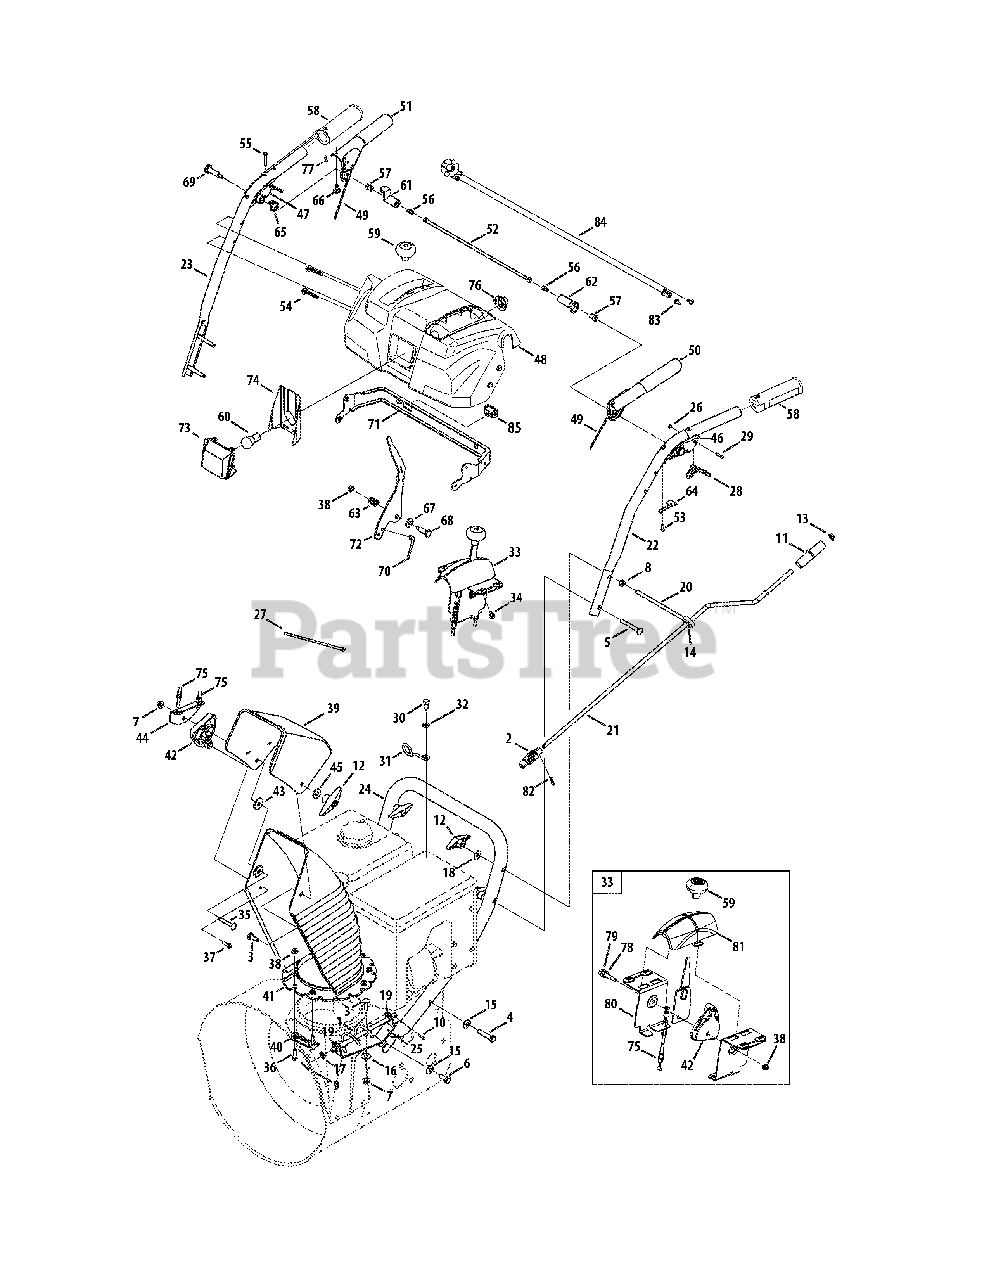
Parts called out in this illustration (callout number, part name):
1	Chute Crank Assembly
2	Joint Block Assembly
3	Screw, Carriage, 5/16-18 x 1.0
4	Screw, Hex, 3/8-16 x 2.00 Lock
5	Screw, Carriage, 5/16-18 x 2.5
6	Screw, Hex, 3/8-16 x 1.0 Lock, Gr5
7	Flange Lock Nut, 5/16-18
8	Hex Nut, 5/16-18
9	Pin, Bow-tie Cotter
10	Spring Pin
11	Knob, Crank
12	Wing Knob
13	Cap, Push, 3/8
14	Grommet, Rubber
15	Washer, Bel, .375 x .87 x .063
16	Washer, Flat, .349 x .879 .063
17	Washer, .375 x .738 x .063
18	Washer, Belleville, .34 x .872 x .06
19	Plastic Bushing, .380 I.D.
22	Handle, Upper - LH
23	Handle, Upper - RH
24	Handle, Lower
25	Chute Crank Bracket
26	Ring, Retainer
27	Cable Tie
30	Hex Head Screw, MB 1.25
31	Cable Guide
32	Flat Washer, .330 x .630 x .0635
33	2-Way Chute Control™ Assy
34	Hi-Lo Screw, 1/4-15 x 0.5
35	Bolt, Carriage, 5/16-18 x 1.75
36	Screw, 1/4-20 x 1.00
37	Hi-Lo Screw, 1/4-15 x .75
38	Flange Lock Nut, 1/4-20
39	Upper Chute
40	Chute, Flange Keeper
41	Lower Chute
42	Chute Tilt Cable Guide
43	Flat Washer
44	Cable Bracket
45	Washer, Flat, .349 x .879
46	Handle Clutch Lock - LH
47	Handle Clutch Lock - RH
48	Handle Panel
49	Cable Assembly, Auger/Drive
50	Handle Engage Assy - LH
51	Handle Engage Assy - RH
52	Rod Ass’y, Clutch Lock Pivot
53	Screw, #8-16 x 0.50
54	Screw, 1/4-20 x 1.625
55	Screw, #10-24 x 0.375
56	Screw, 1/4-20 x.375
57	Shoulder Nut, 1/4-20
58	Heated Grip
59	Shift Knob
62	Clutch Lock Cam
63	Compression Spring
64	Clutch Lock Spring
65	Torsion Spring
66	Rubber Bumper
67	Flat Washer, .385 x .87 x .06
68	Shoulder Screw
69	Shoulder Screw, 1/4-20 x 1.345
70	Speed Selector Cable
73	Lens Panel
74	Reflector Label
75	Cable, Chute Tilt
76	Light Socket
77	Screw, #10-16 x .625
78	Washer, Spring, .39 x .625 x .012
79	Screw, Shoulder, .31 x .995:1/4-20
80	Bracket, Mounting
81	Cover, Tilt Cover
82	Internal Cotter Pin
83	1/4-20 x .50
84	Wire Harness
85	Heated Grip Switch
